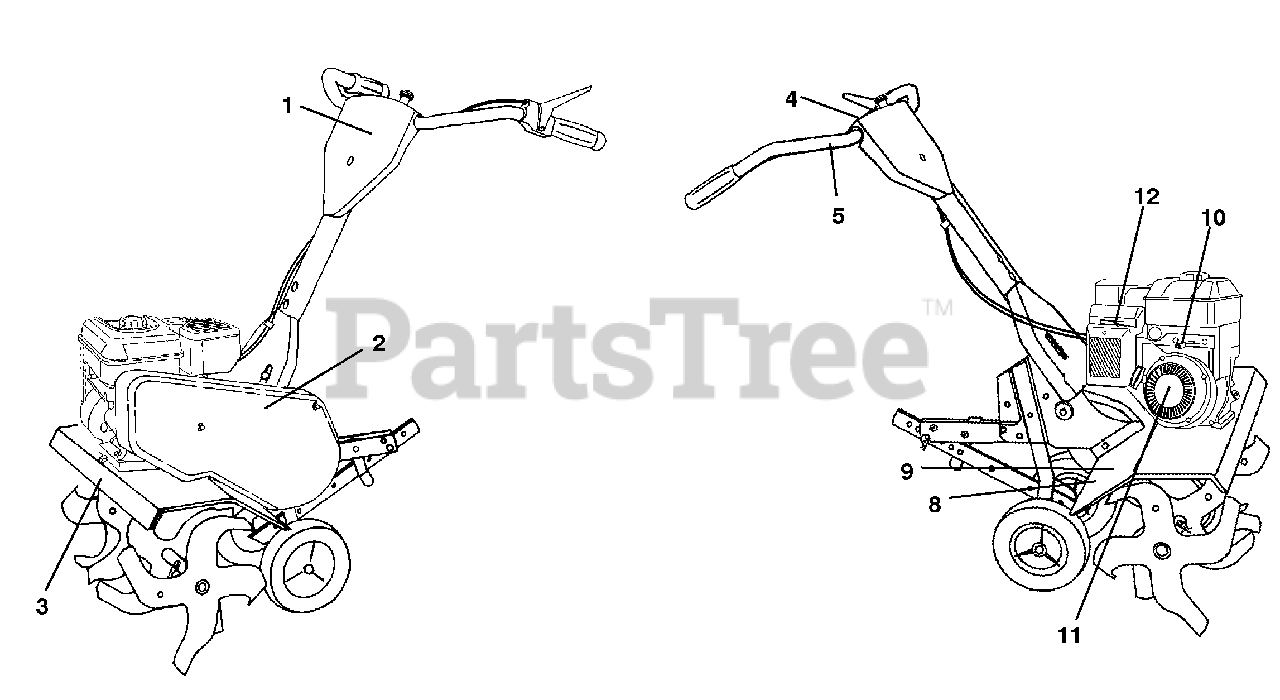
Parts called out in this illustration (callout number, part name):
1	Decal, Logo
2	Decal, Logo
3	Decal, Logo
4	Decal, Panel Control Inst.
5	Decal, Hand Placement
8	Decal, Warning, Rotating Tines
9	Decal, Tine Shield
10	Decal, Tank
11	Decal, Recoil
12	Decal, Engine AC
